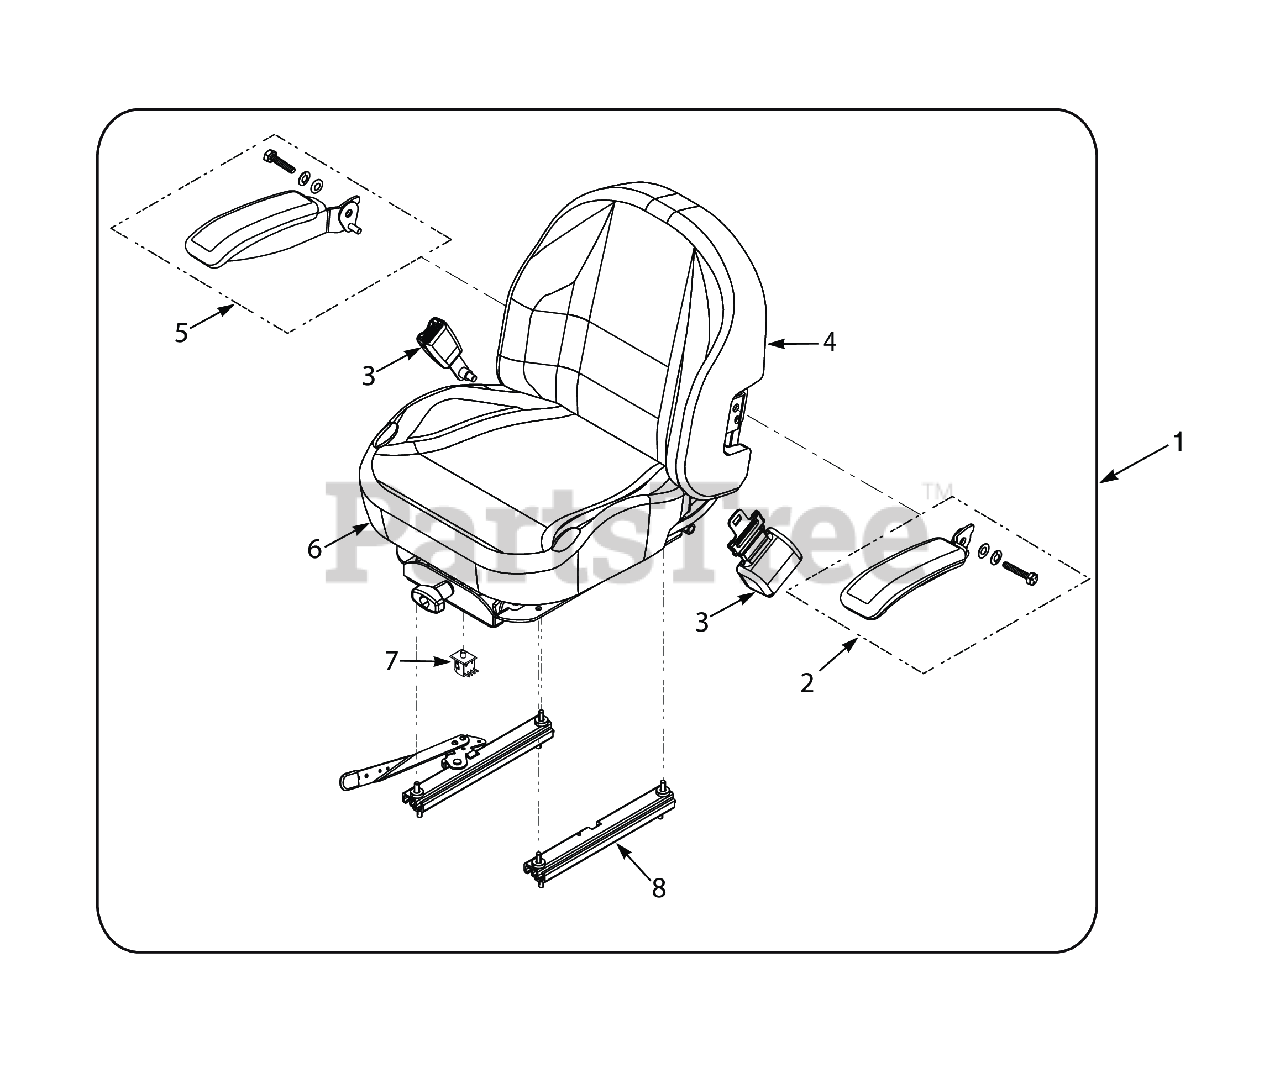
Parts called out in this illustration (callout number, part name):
1	Seat Assembly
2	Armrest Kit, LH
3	Seat Belt Kit (Soft Ride Seat)
4	Back Cover
5	Armrest Kit, RH
6	Cushion Cover
7	Switch, Double Pole - Plunger
8	Track Set
